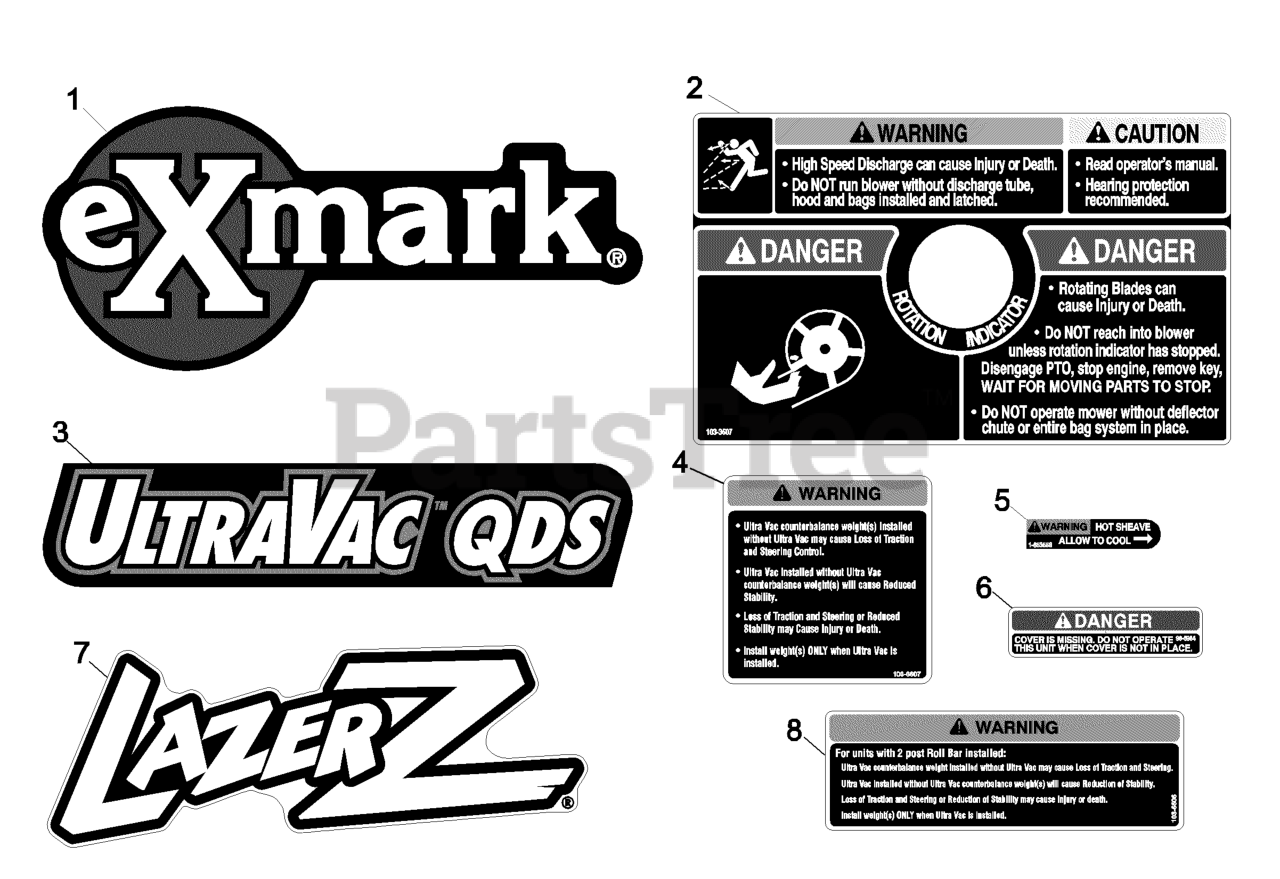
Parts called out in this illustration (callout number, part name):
1	DECAL, EXMARK
3	DECAL, ULTRAVAC QDS
4	DECAL,WEIGHT
5	DECAL-WARNING
6	DECAL-COVER, MISSING
7	DECAL,LAZER MODEL
8	DECAL,WEIGHT
